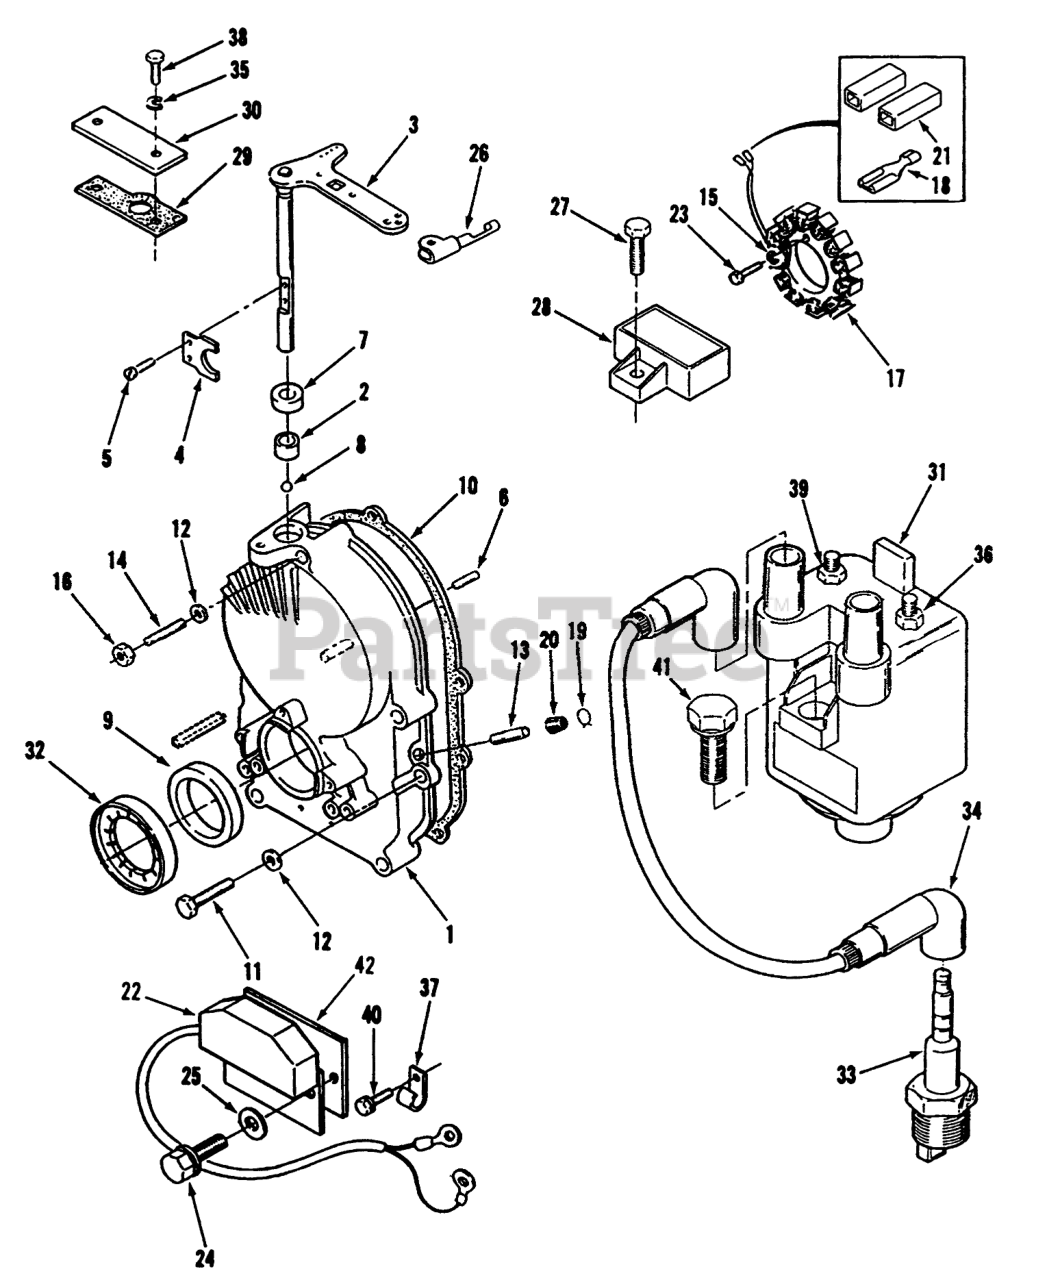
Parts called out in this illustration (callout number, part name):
1	Kit-Gearcase (Incl.Ref.#2-9,13,19,&20)
2	BEARING
3	SHAFT AND ARM
5	SCREW-PAN HD
6	Washer
8	Bearing
10	Gasket
11	Bolt
12	WASHER
13	TUBE-PORT, VACUUM
14	Stud
15	WASHER-LOCK
16	Nut
17	Stator w/Terminals
18	Stator Leads Terminal
19	CLAMP
20	CAP-FUEL OUTLET
21	BODY-TERM. CONNECTOR KIT
22	Control-Ignition
23	Screw-HH
24	Bolt
25	WASHER-LOCK
27	Bolt
28	Regulator
29	Gasket-Plate
30	Plate
31	Coil-Ignition
32	Rotor
33	SPARK PLUG
34	WASHER-FLAT
35	WASHER-FLAT
36	Nut
37	Clip
38	SCREW - CAP HEX HEAD
39	Nut
40	Bolt
41	Bolt
42	Insulator
